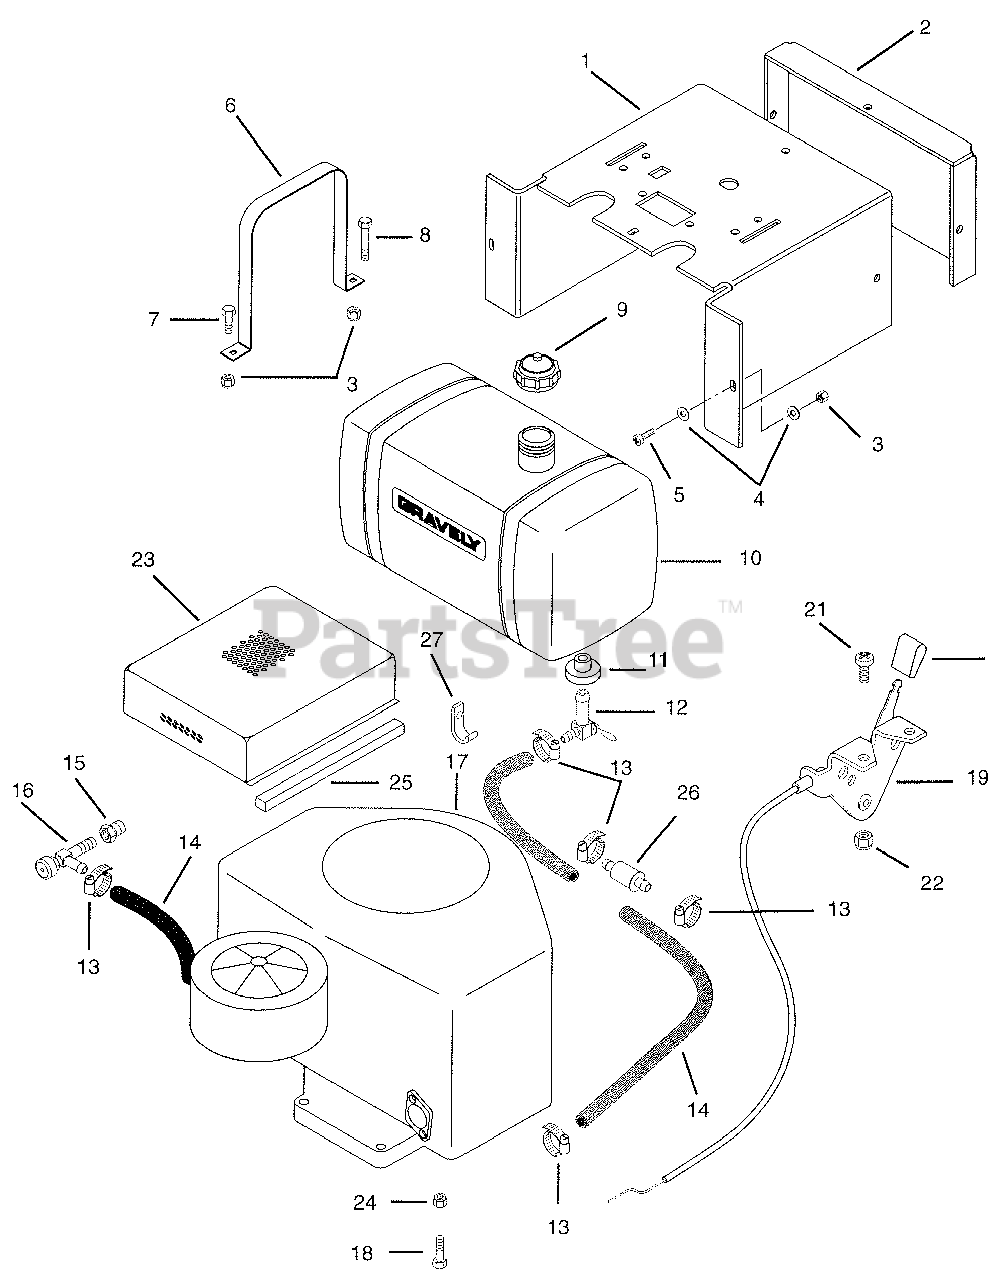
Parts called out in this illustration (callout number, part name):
1	Panel, Silkscreen (007, 008, 009, 012, 302)
2	Cover, Instrument Panel
3	Nut Locking Nylon .250-20 Grade 2
4	Washer Flat Steel .281 X .620 X .065
5	Screw Machine .25-20
6	Strap, Fuel Tank
7	Bolt Hex .25-20 X .63
8	Bolt Hex .25-20 X 1.00 Grade 5
9	Cap, Fuel Tank
10	Tank, Fuel PM 200
12	Fitting, Tank
13	Hose Clamp
14	Gas Line Bulk
15	Adapter, Oil Drain (007, 008, 009, 012, 302)
16	Cock, Oil Drain
17	Engine, 20 HP Kohler CV20S (008,9,302)
18	Screw Tapping .375-16 X 1.0 (007, 008, 009, 012, 302)
19	Assembly, Throttle Control (007, 008, 009, 012, 302)
21	Screw Machine 10-32 X .50
22	Nut Locking 10-32
23	Weldment, Pre Cleaner Screen (010, 011)
24	Nut Hex M8 X 1.25 (010, 011)
25	Pad, Pre Cleaner Screen (010, 011)
26	Filter, Fuel (010, 011)
